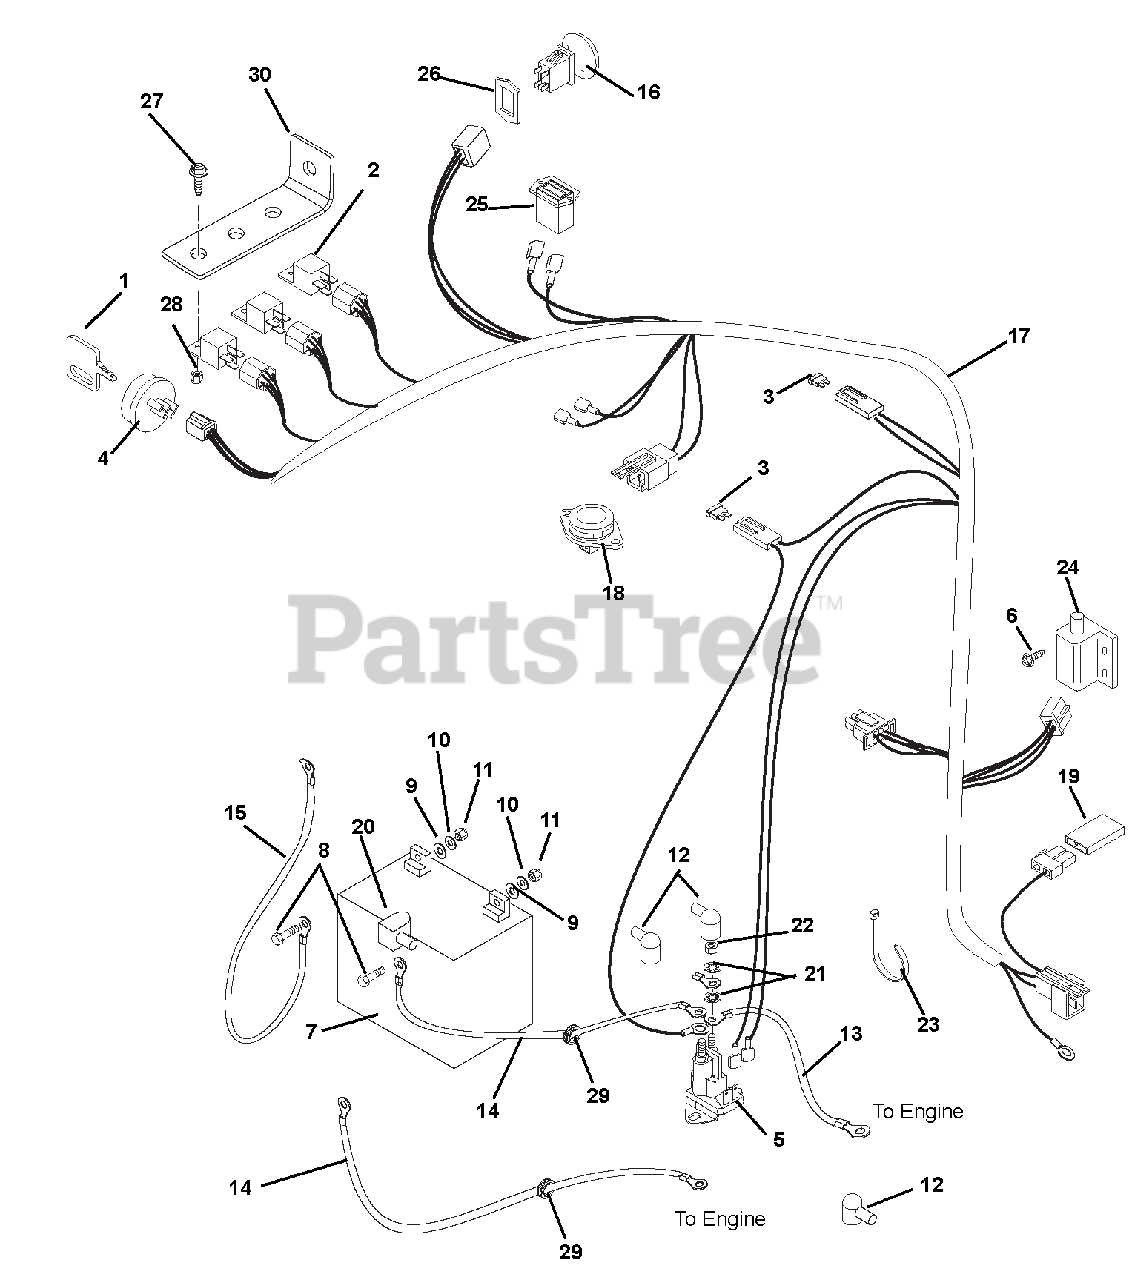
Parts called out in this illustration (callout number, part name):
1	KEY -W/CAP
2	RELAY,SEALED W/DIODE
3	FUSE-25 AMP ATC TYPE
4	KEY SWITCH
5	SOLENOID, HP RTV
6	@SCR-TAP 10-24X.50 HWH TR YWZC
7	BATTERY, 300 CCA 10U1L
8	@BLT-HEX .25-20X.75 GR5 YWZC
9	@WSHR-FL-STL.281X.62X.065 YWZC
10	@WSHR-LK .25X.062 REG YWZC
11	@NUT-HEX .25-20 YWZC
12	BOOT, EYELET TERMINAL
13	STARTER CABLE 6.75"
14	STARTER CABLE 16"
15	GROUND CABLE .31X22.00X.31
16	SWITCH, CLUTCH
17	WIRE HARNESS, ZT XL/ZOOM CE
18	SWITCH- SNAP MTG N.O.
19	DIODE, CONNECTOR SHELL
20	INSULATOR
21	WSHR-LOCK INT .31 YWZC
22	NUT-JAM .31-24 YWZC
23	CABLE TIE LG 5-1/2
24	SWITCH- DOUBLE POLE N.O./N.O.
25	HOURMETER-QUARTZ 80VDCMAX
26	SHIM,PTO SW (DELTA #972301)
27	@SCR-MCH 10-24X.50 HWH YWZC
28	@NUT-LK-NYL 10-24 W/INSRT YWZC
29	GROMMET 1.0ID X 1.38 OD
30	BRACKET, RELAY
